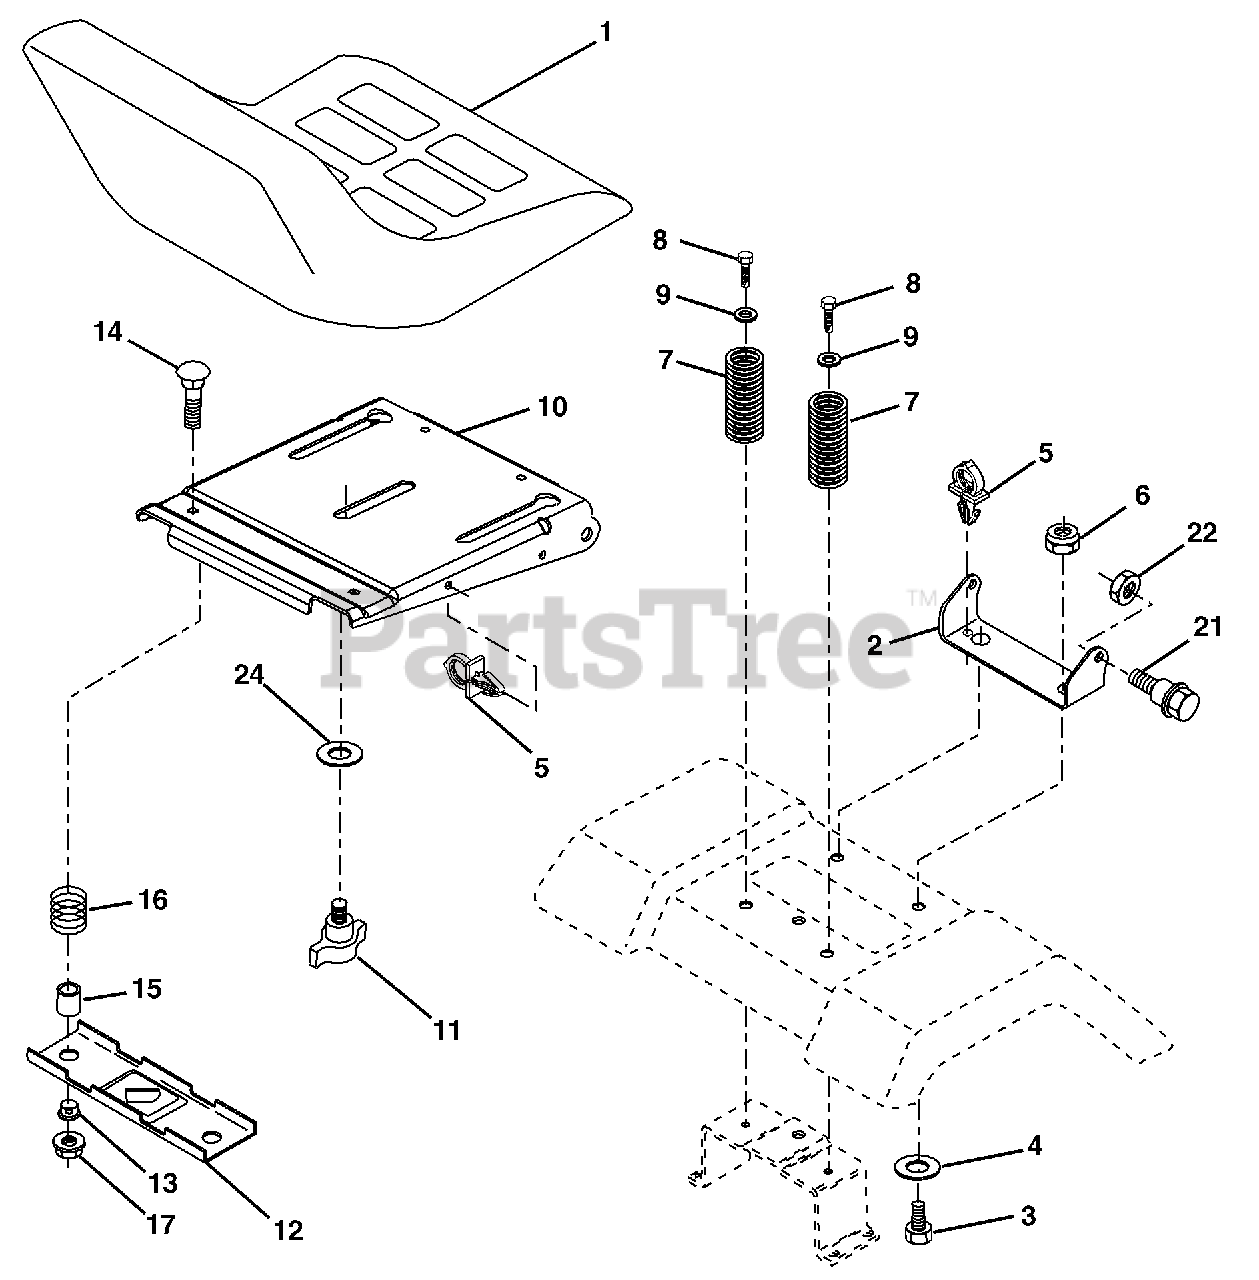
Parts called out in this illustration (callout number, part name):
1	Seat
2	Bracket Pivot Fender
3	Bolt Fin Hex 3/8-16 unc x 1
4	Washer 13/32 x 1 x 10 Ga.
5	Clip Push-In
6	Nut Hex w/Ins. 3/8-16 unc
7	Spring Seat Cprsn 2 250 Blk Zi
8	Screw 3/8-16 x 1.5 Smgml
9	Washer 13/32 x 1 x 14 Ga.
10	Pan Seat
11	Knob Seat
12	Bracket Mounting Switch
13	Bushing Snap Blk Nyl 50 Id
14	Bolt Rdhd Sqnk 1/4-20 x 1-1/2
15	Spacer Split 28x 88
16	Spring Cprsn
17	Nut Lock 1/4 Lge Flg Gr. 5 Zinc
21	Bolt Shoulder 5/16-18 unc
22	Nut Hex Lock W/Ins 5/16-18
24	Washer 17/32 x 1-3/16 x 12 Ga.
